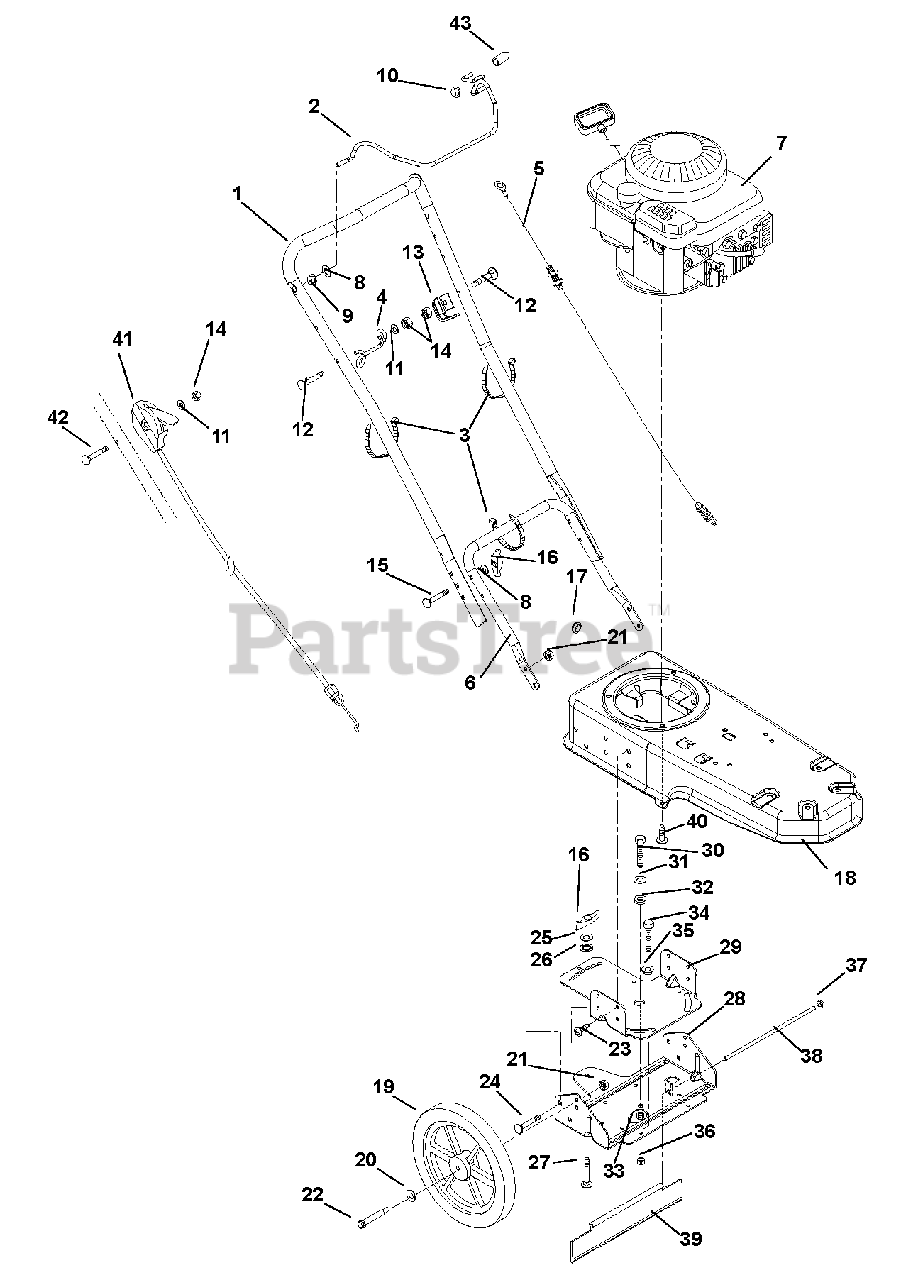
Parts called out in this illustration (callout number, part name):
1	Handlebar-Upper
2	Bail-Clutch Control
3	Cable-Tie
4	Guide-Pullcord
5	Cable-Control
6	Handlebar-Lower
7	Briggs & Statton 6.25hp Trim Engine
8	Washer-Flat-Steel .344 x .688 x .065
9	Bushing-Flange .325 x .444 x .440 x .560
10	Nut-Push .25
11	Washer-Flat-Steel .281 x .62 x .065
12	Bolt-Round Head Extra Long Square Neck .25-20 x 1.25
13	Cable-Anchor
14	Nut-Locking-Center .25-20
15	Bolt-Round Head Square Neck Full Thread .31-18 x 2.00 Grade 5
16	Knob-Wing .312-18
17	Grommet .50 I.D.
18	Frame-Trimmer
19	Wheel, 14" String Trimmer
20	Washer-Flat-Steel .52 x .827 x .062
21	Nut-Locking-Center .38-16
22	Bolt-Shoulder .38-16 x 2.50
23	Screw-Tapping .38-16 x .75
24	Bolt-Round Head Square Neck .38-16 x .75 Grade 5
25	Washer-Flat-Steel .38 x .875 x .083
26	Nut-Push .312
27	Bolt-Round Head Square Neck .31-18 x 1.00
28	Bracket-Axle Swivel
29	Base-Swivel
30	Bolt-Hex .50-13 x 1.00 Grade 5
31	Washer-Flat-Steel .562 x 1.38 x .109
33	Nut-Locking-Center .50-13
34	Bolt-Hex .31-18 x 1.00
35	Bushing Flange .312 x .500 x .344 x .880
36	Nut-Locking-Center .31-18
37	Nut-Push .312
39	Guard-Rear-Swivel
40	Screw-Tapping .38-16 x 1.00
41	Cable, Throttle
42	Bolt-Round Head Extra Long Square Neck .25-20 x 1.75
43	Cap-Vinyl .25 I.D.
